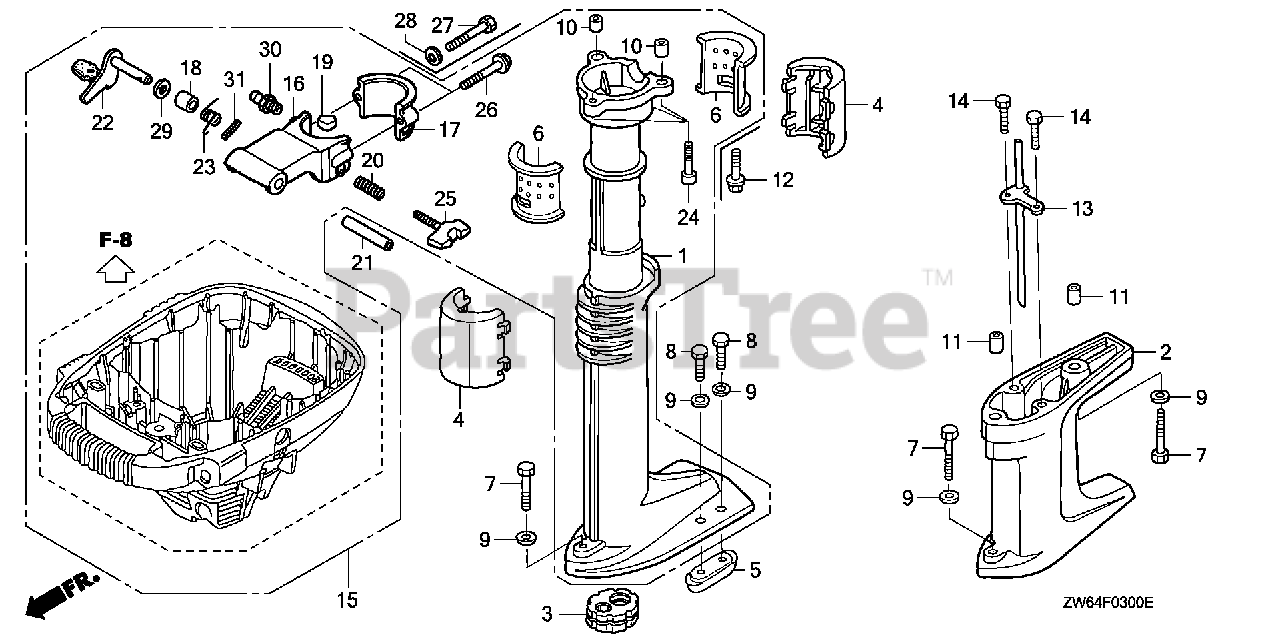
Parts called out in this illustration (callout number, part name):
3	BUSH, VERTICAL SHAFT (S)
5	METAL, ANODE
7	BOLT, HEX. (6X35)
8	BOLT, HEX. (6X16)
9	WASHER, PLAIN (6MM)
10	PIN, DOWEL (8X10)
12	BOLT, FLANGE (6X25)
15	CASE KIT, EXTENSION *NH246* (LOOSY GRAY)
19	BLOCK, FRICTION
